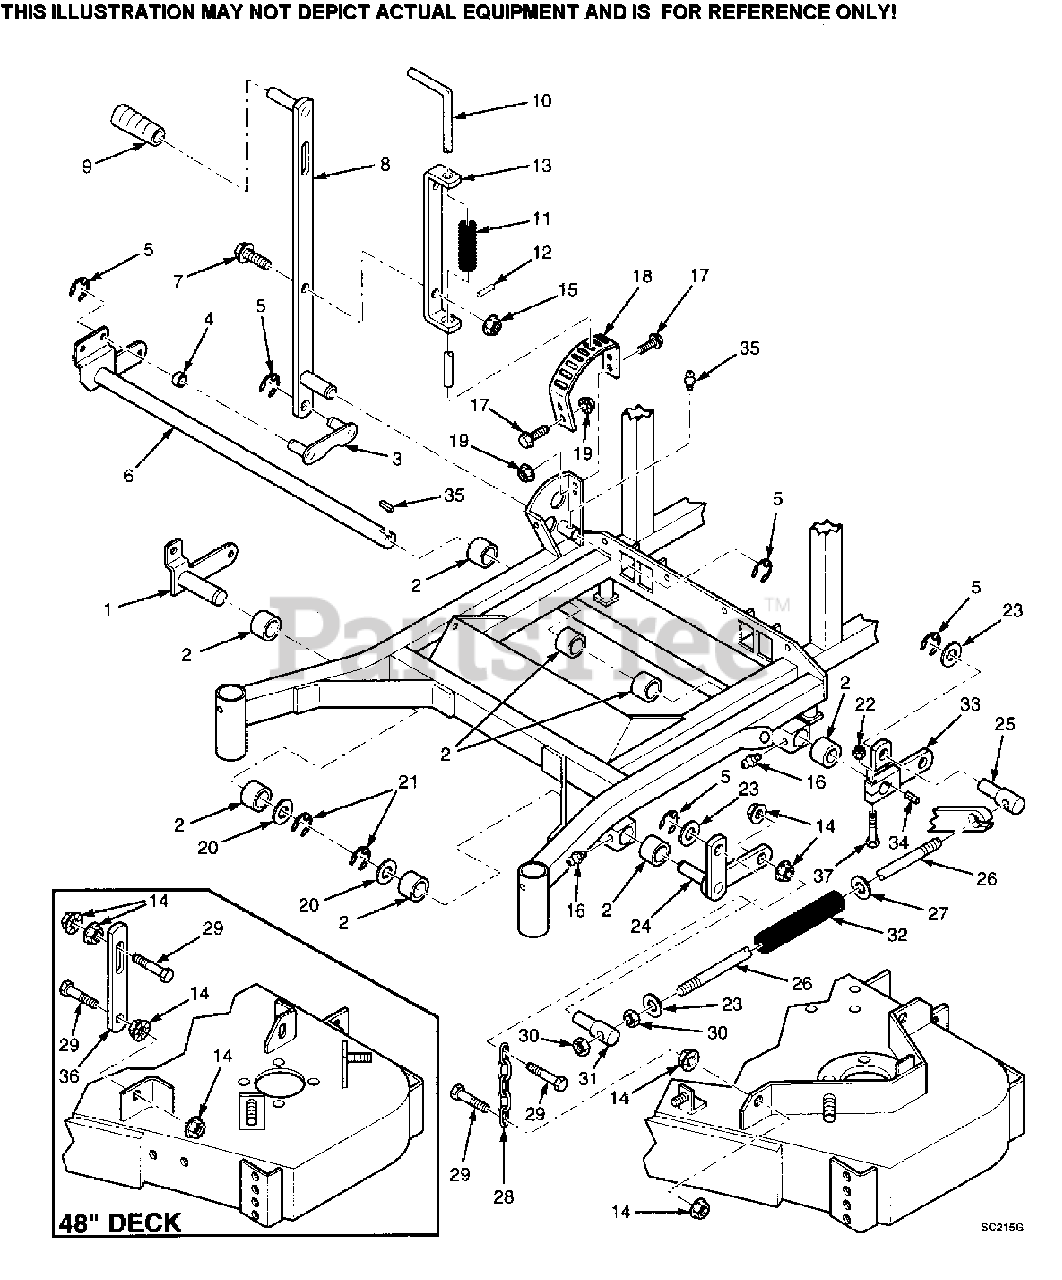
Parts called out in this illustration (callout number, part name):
1	BELLCRANK, LIFT - RIGHT FRONT
2	BUSHING
3	LIFT LINK
7	BOLT, SERRATED FLANGE HEX HEAD 5/16-18 X 1"
8	HEIGHT ADJUSTMENT LEVER(INCLUDES GRIP)
9	GRIP, LEVER LIFT
10	ROD, CUTTER DECK LOCK
11	SPRING, DECK LIFT INDEX
13	LOCK, ROD GUIDE
14	NUT, SERRATED FLANGE HEX 3/8-16
16	GREASE FITTING
18	STRIP, HEIGHT ADJUSTMENT
22	NUT, ELASTIC STOP 3/8-16
23	FLATWASHER, 5/8"(.656 X 1.312 X .075)
24	BELLCRANK, LIFT - LEFT FRONT
25	SWIVEL JOINT - LH THD
27	FLATWASHER, 5/8"(.688 X 1.75 X .134)
29	BOLT, HEX HEAD 3/8-16 X 1-1/2"
30	NUT, HEX 5/8-11
31	SWIVEL JOINT - RH
33	BELLCRANK
34	KEY, 3/16 X 3/16 X .75"
35	GREASE FITTING
37	BOLT, HEX HEAD 3/8-16 X 2"
